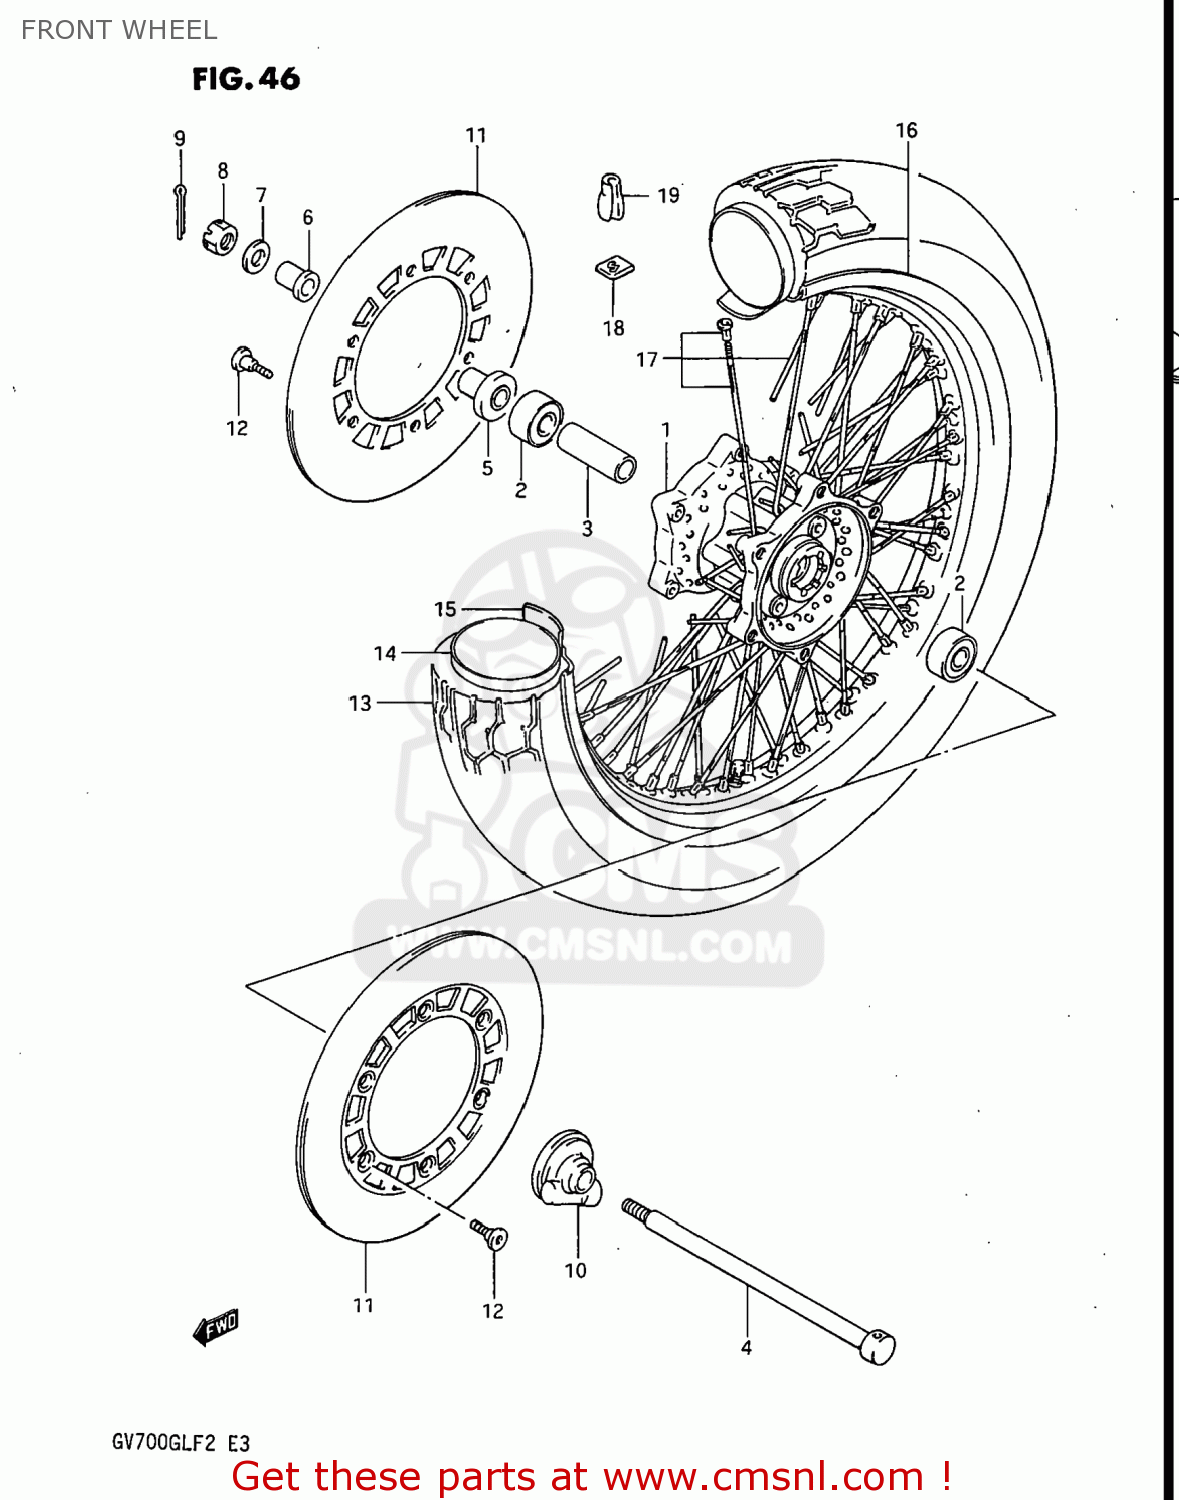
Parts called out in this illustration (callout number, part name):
1	HUB,FRONT
2	BEARING
3	SPACER
4	AXLE,FR
5	SPACER,FRONT AXLE,RIGHT
6	SPACER,FRONT AXLE,RIGHT
7	WASHER
8	NUT, REAR AXLE
9	COTTER PIN
10	BOX ASSY,SPEEDOMETER GEAR
11	DISC,BRAKE
12	BOLT(8X25.5)
13	TIRE 110/80-19
14	TUBE,INNER
15	PROTECTOR,WHL INR TUBE
16	RIM,FRONT WHEEL (2.50X19)(
17	SPOKE SET,FRONT
18	BALANCER,WHEEL NO.1
19	BALANCER,WHEEL
